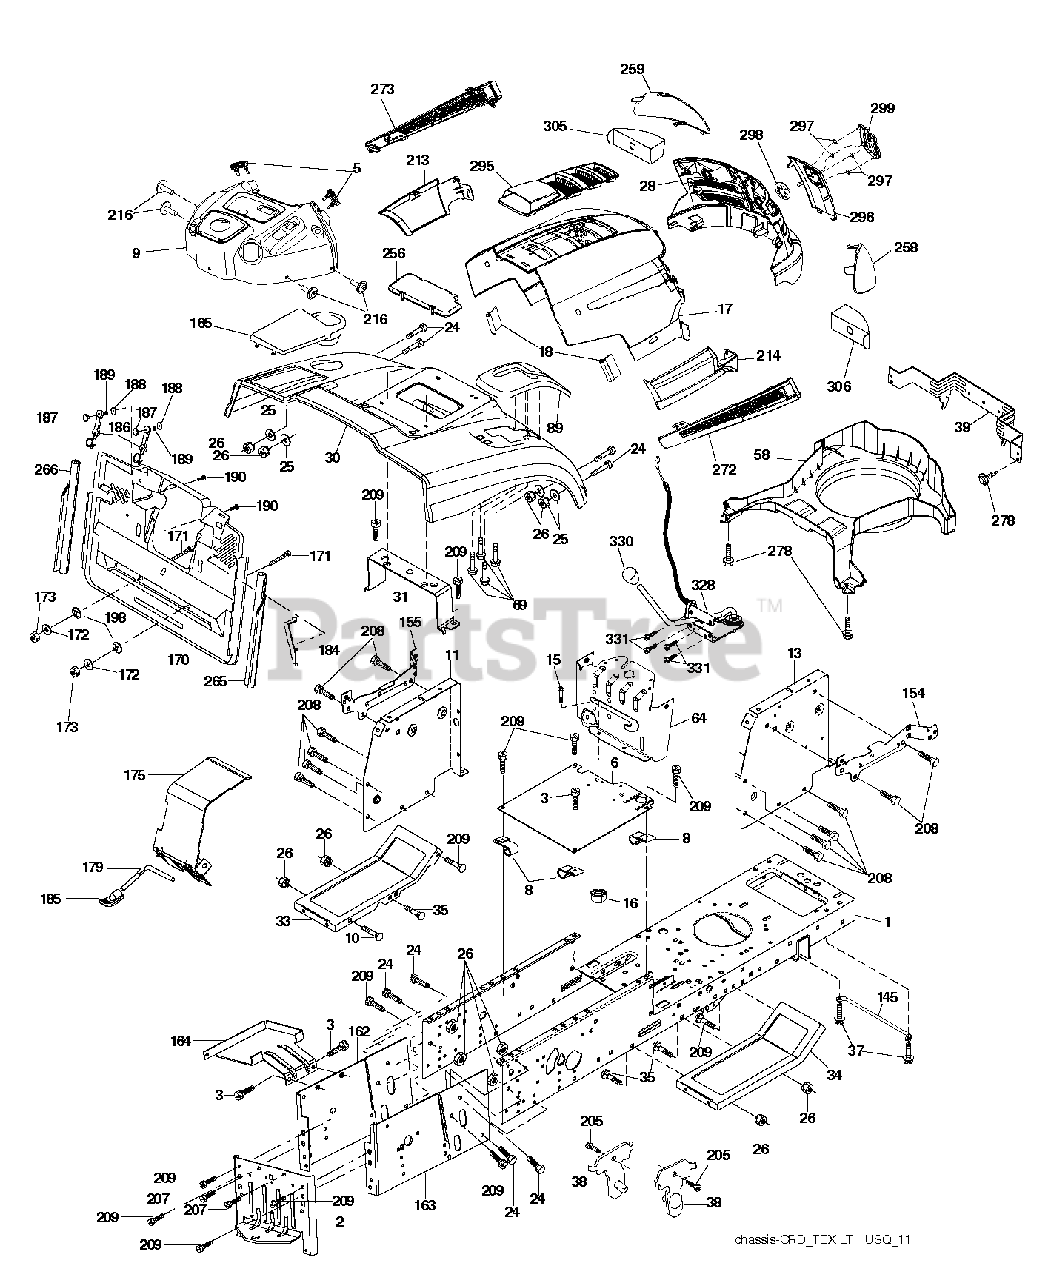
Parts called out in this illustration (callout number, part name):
2	DRAWBAR
3	SCREW 3/8-16X3/4
5	BUMPER DASH
6	PLATE
8	CLIP,INSULATOR
10	BOLT D
11	PANEL.DASH.LH.LTX
13	PANEL ASM, DASH RH
16	NUT
17	HOOD.HUSQVARNA.LT.ORANGE
18	BUMPER.HOOD.TEX.HUSQVARNA
24	BOLT
25	WASHER
26	NUT
28	GRILLE.SVC.HUSQVARNA.LT.GREY
30	FENDER.PNT.CRD.MS-668
31	BRACKET SUPPORT FENDER
33	FOOTREST PNT LH
34	FOOTREST PNT RH
35	BOLT
37	SCREW LT
38	BRACKET ASM PIVOT MOWER REAR
39	BRACKET PIVOT
69	SCREW.HI-LO.CONSOLE
89	CONSOLE.CRD.AUTO.GRY
145	ROD.PIVOT.HOOD
162	BRACKET
163	BRACKET EXTEN CHASSIS RH CRD
165	RP COVER.BATTERY.CRD.GREY
171	BOLT
172	WASHER
175	DOOR TRAP
179	ROD PIVOT FBI
184	BRACKET.ACTUATOR.BAGGER.SRD
185	KNOB.BRAKE.PARKING.ROD
186	LATCH ASSY
187	WELDNUT
189	LOCKWASHER (3 2)
190	SCREW
205	SCREW LT
207	SCREW, 5/16-18 X 1/2
208	SCREW 3/8-16X1/2
209	SCREW, 3/8-16X3/4
213	SKIRT.SIDE.HUSQVARNA.LT.LEFT
214	SKIRT.SIDE.HUSQVARNA.LT.RT
216	SCREW HEXWSHR 1/4-20X3/4
256	FENDER.PNT.CRD
258	LENS.HUSQVARNA LT.RH
259	LENS.HUSQVARNA LT.RH
265	SEALING
266	SEALING
272	VENT.SIDE.HUSQVARNA.LT.LFT
273	VENT.SIDE.HUSQVARNA.LT.RT
278	SCREW.#10 X 0.750.BOS
295	SUBASM.TOP.VENT.HUSQ.LT
296	SUBASM.TOP.VENT.HUSQ.LT
297	CLIP.RETAINER.TINNER.
298	NUT PUSH M
299	RP LOGO
305	INSERT REFLECTIVE
306	INSERT.REFLECTIVE.RH.
330	RP KNOB.OVAL.TAPERED.3/8-16BLK
331	SCREW.#10-24X5/8.RN.QU
